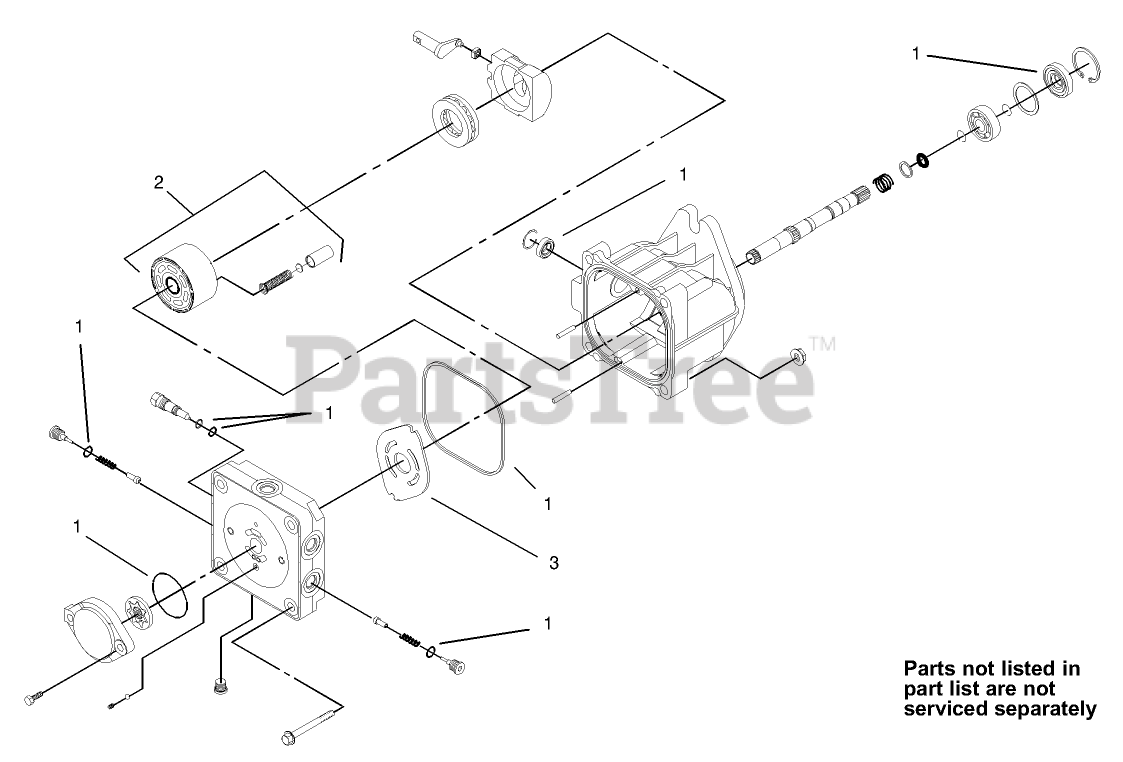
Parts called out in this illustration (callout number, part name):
1	OVERHAUL SEAL KIT
2	KIT-BLOCK, CYLINDER
3	PLATE-VALVE
